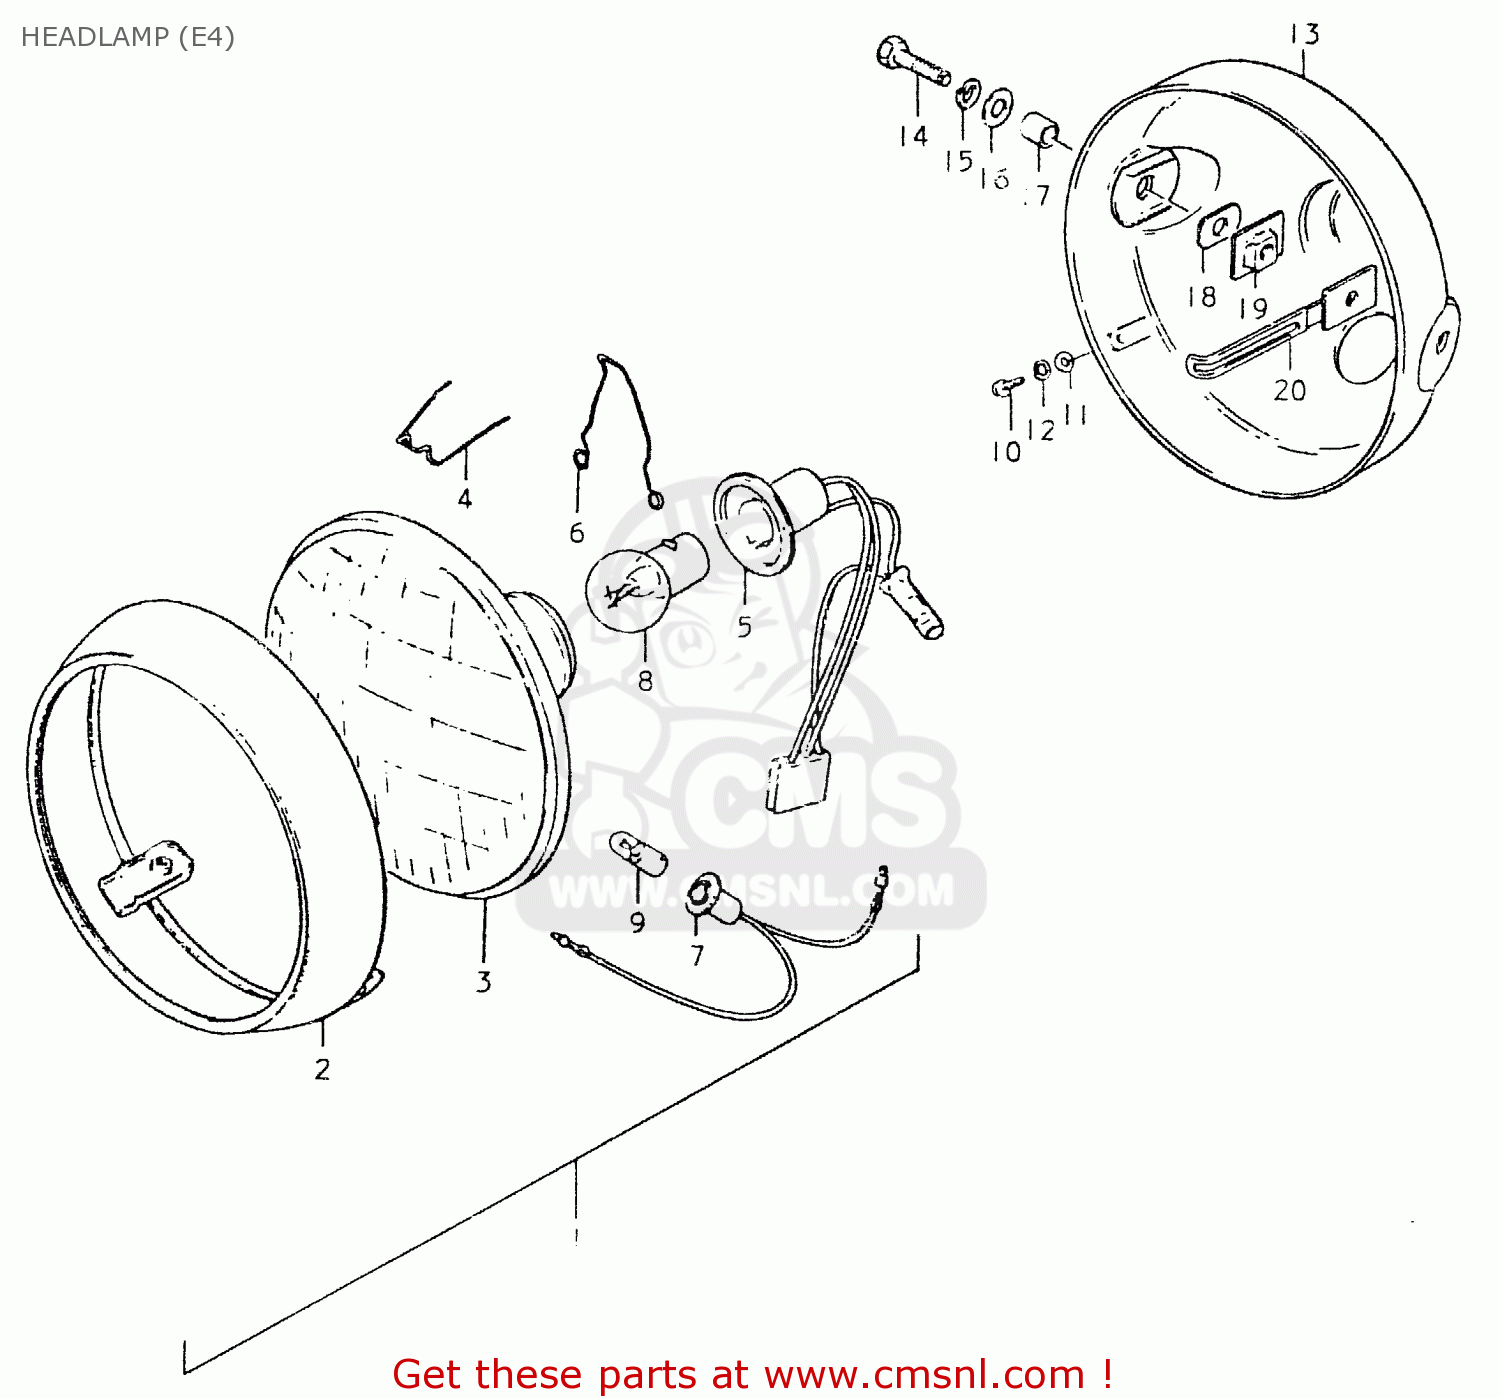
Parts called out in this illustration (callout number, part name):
1	HEADLAMP ASSY
2	RIM
3	UNIT
4	SPRING
5	SOCKET
6	CLAMP,HEADLAMP
7	SOCKET
8	BULB (6V,36/36W)
9	BULB (6V,4W)
10	SCREW
11	WASHER
12	LOCK WASHER
13	HOUSING,HEADLAMP
14	BOLT
15	LOCK WASHER
16	WASHER
17	SPACER (8.8X12X7)
18	CUSHION
19	PLATE,HEADLAMP HOUSING
20	PLATE,HEADLAMP HOUSING
